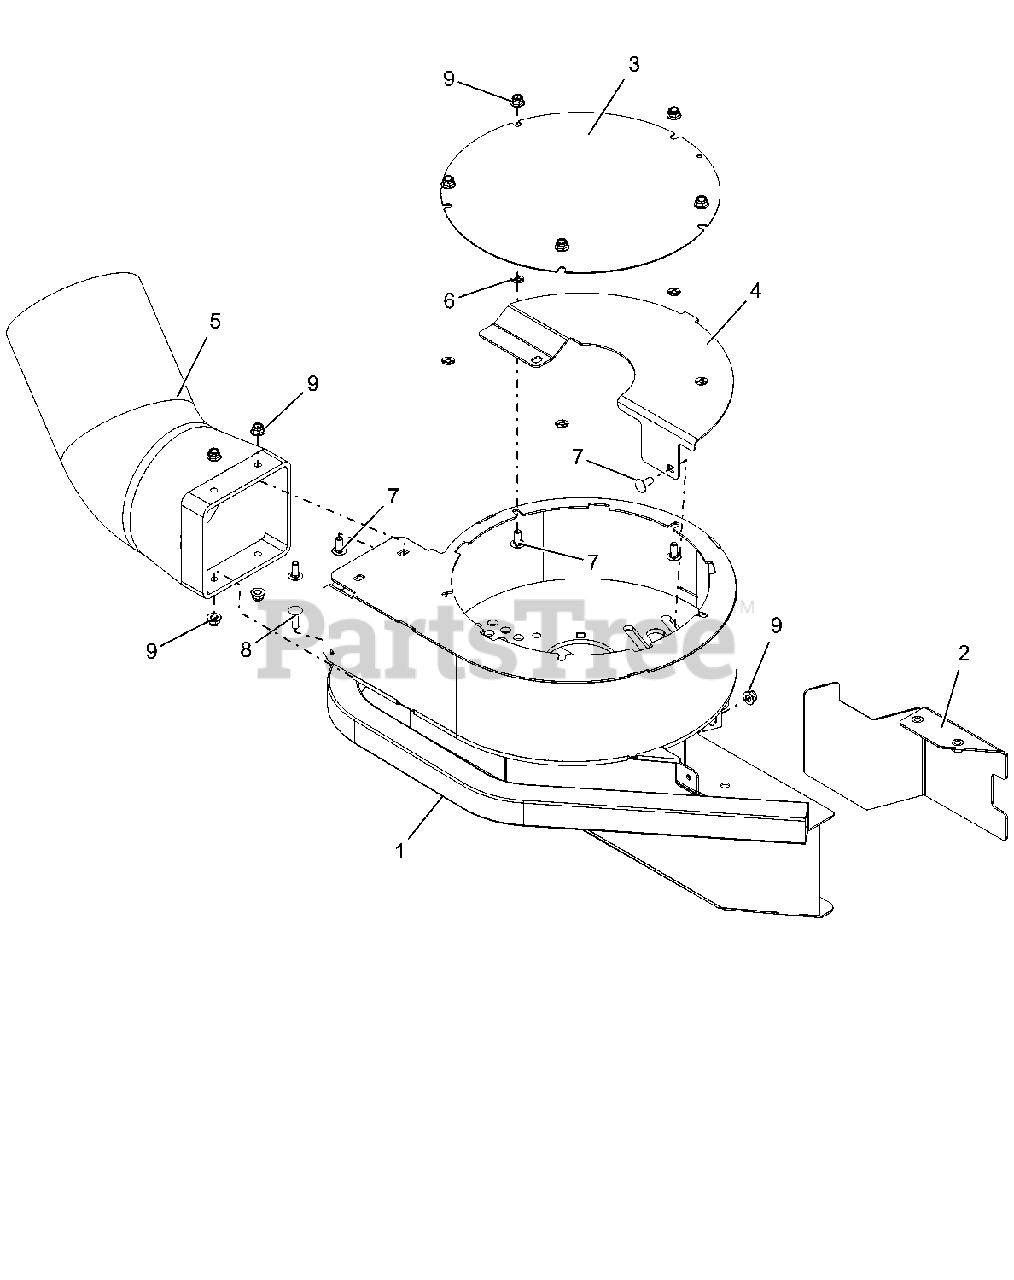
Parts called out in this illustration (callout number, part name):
1	WLDMT, COMM BAGGER BLOWER - RED
2	WLDMT, 52" FRONT BLOWER BAFFLE-BLACK
3	COVER, BLOWER -BLACK
4	COVER, BOTTOM - BLK
5	ADAPTOR, HOSE
6	NUT, PUSH .312
7	BLT-RHDSSQNK .31-18X.75 G5YZ
8	BLT-RDHDSQSHNK .31-18X1.00 G5YWZC
9	NUT-LK-NYL-FLG .31-18 YWZC
